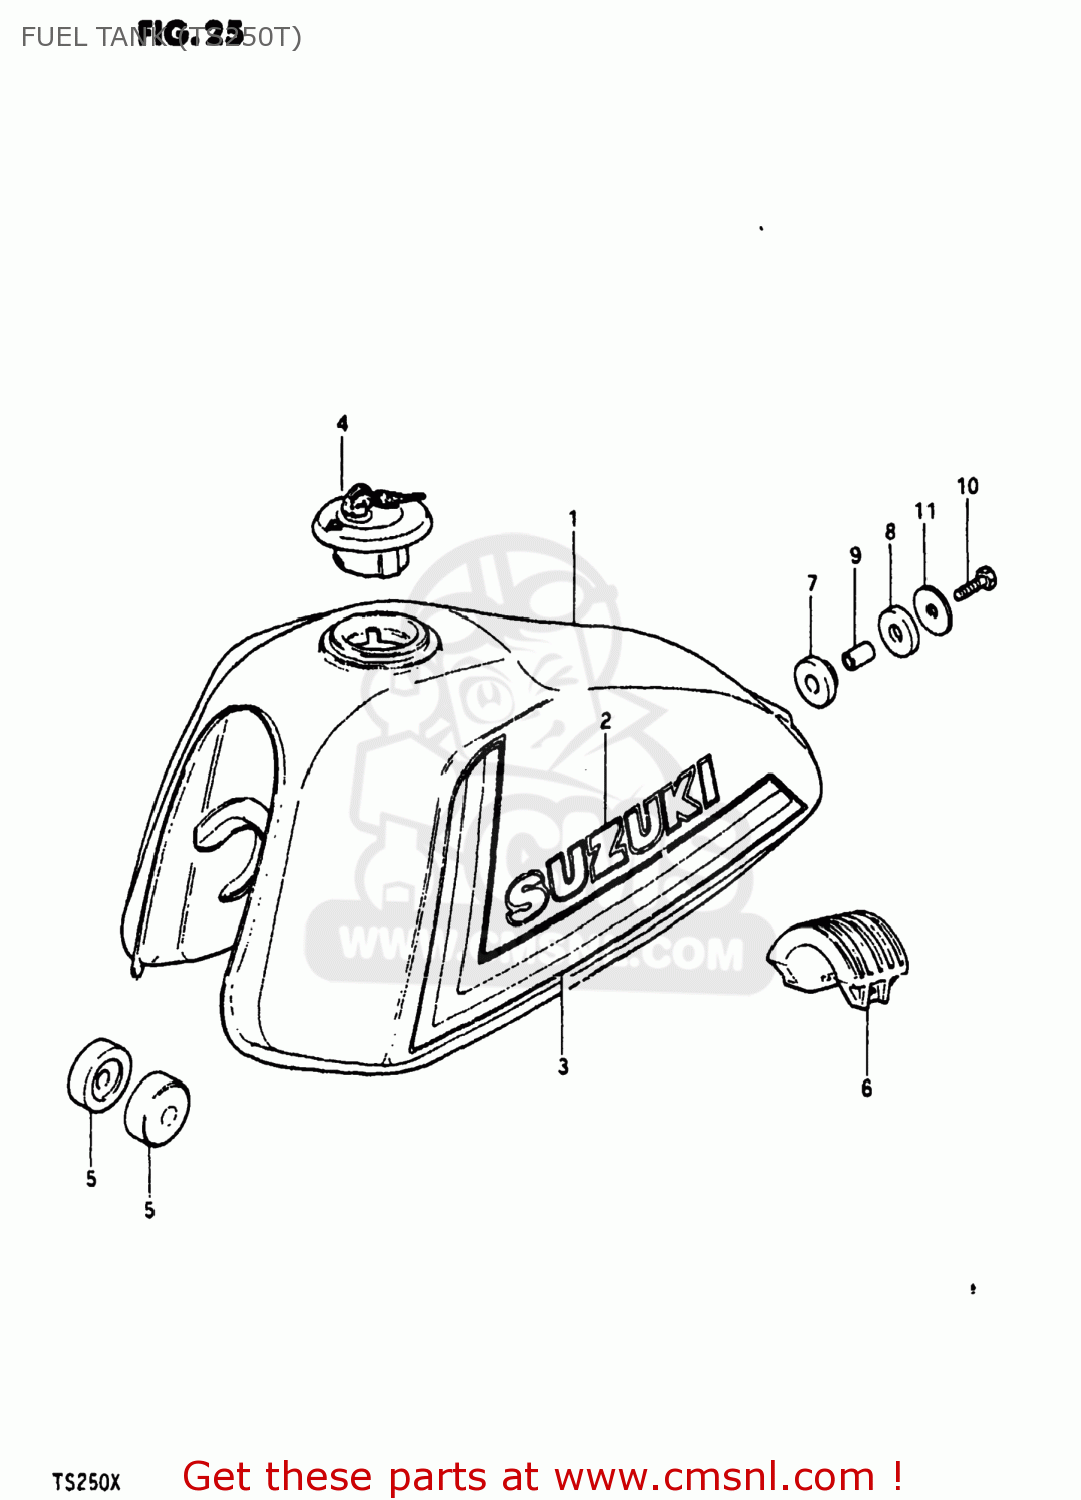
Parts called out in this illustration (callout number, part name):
1	TANK ASSEMBLY,FUEL
2	EMBLEM
3	TAPE SET,FUEL TANK
4	CAP SET,FUEL TANK
5	CUSHION
6	CUSHION,FUEL TANK
7	CUSHION
8	CUSHION
9	SPACER (8.2X12X17)
10	BOLT (8X30)
11	WASHER (8.5X29X1.6)
